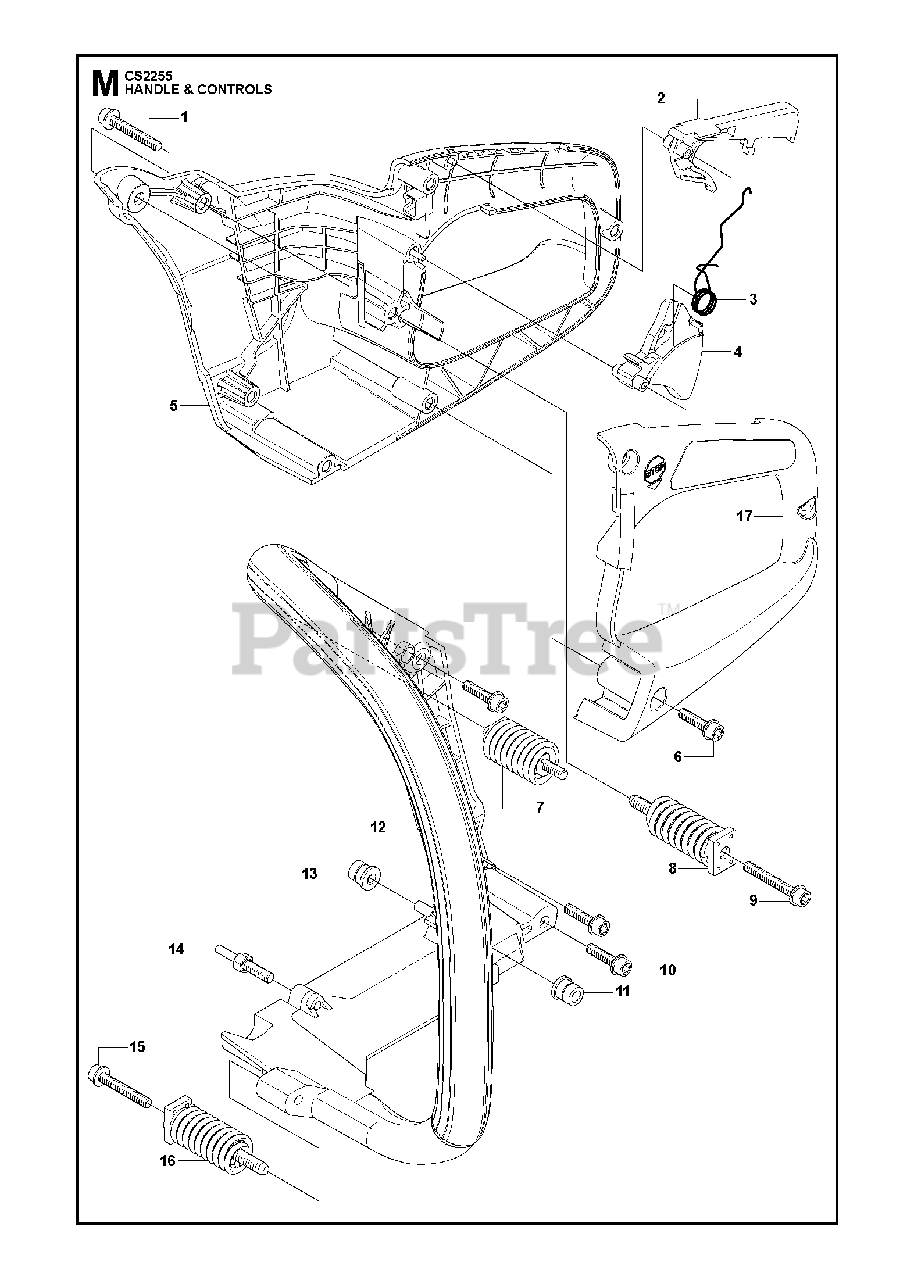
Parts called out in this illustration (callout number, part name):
1	%SCREW
2	THROTTLE LOCKOUT
4	THROTTLE TRIGGER
5	REAR HANDLE
7	VIBRATIONS ABSORBER
8	VIBRATION ABSORBER
11	MOVEMENT LIMITER
12	FRONT HANDLE
13	MOVEMENT LIMITER
